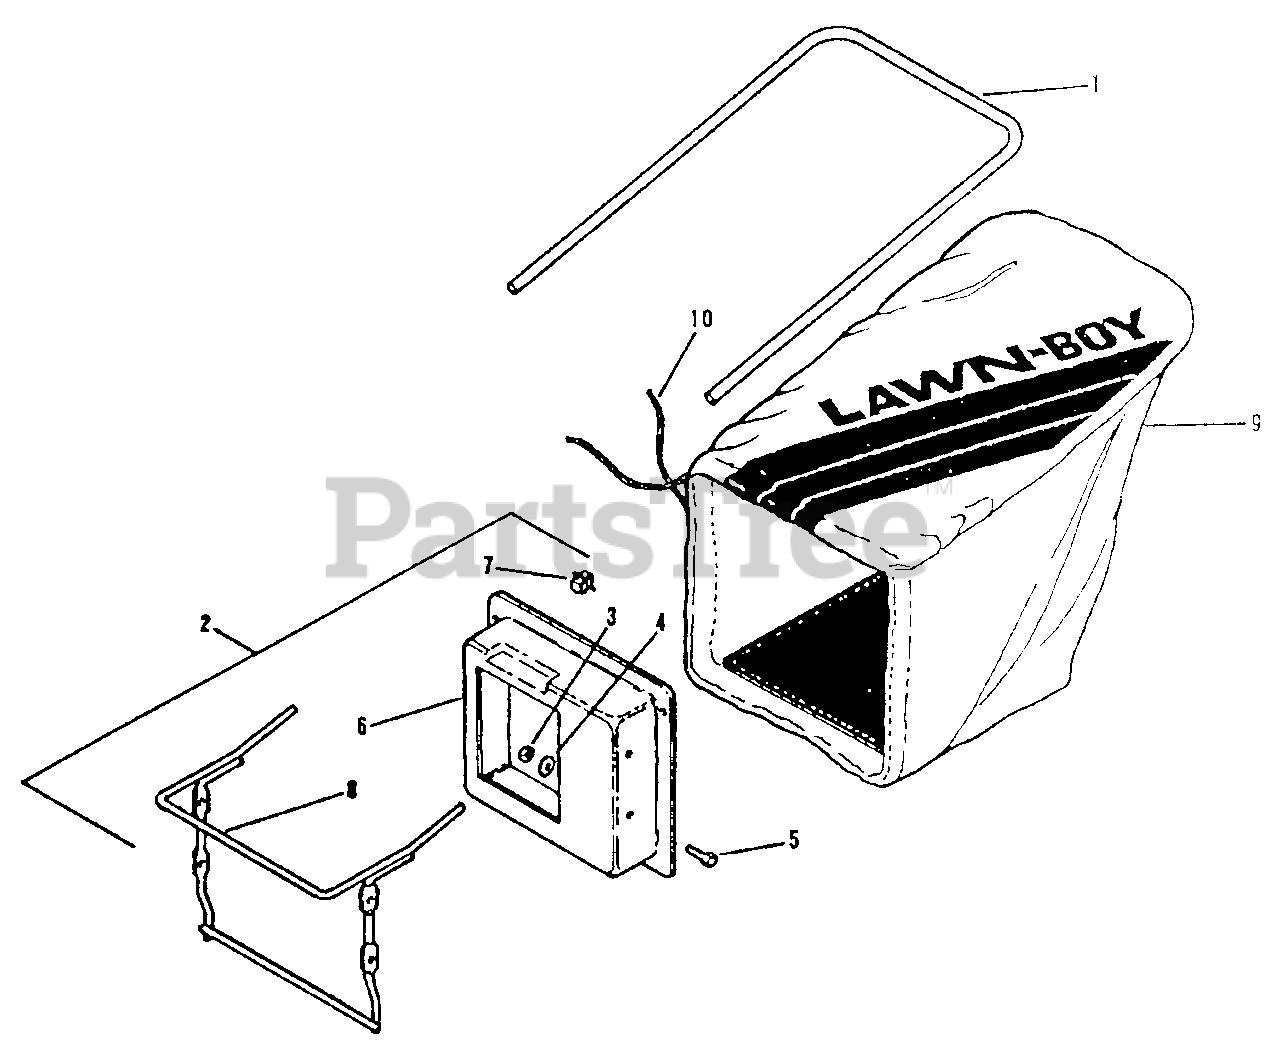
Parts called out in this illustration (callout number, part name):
1	Bag Hanger
2	Bag Adaptor Assembly
3	Locknut
4	Flat Wsaher
5	Screw
6	Adaptor
7	"S" Clip
8	Latch Bar
9	Replacement Bag Assembly
10	Rope
